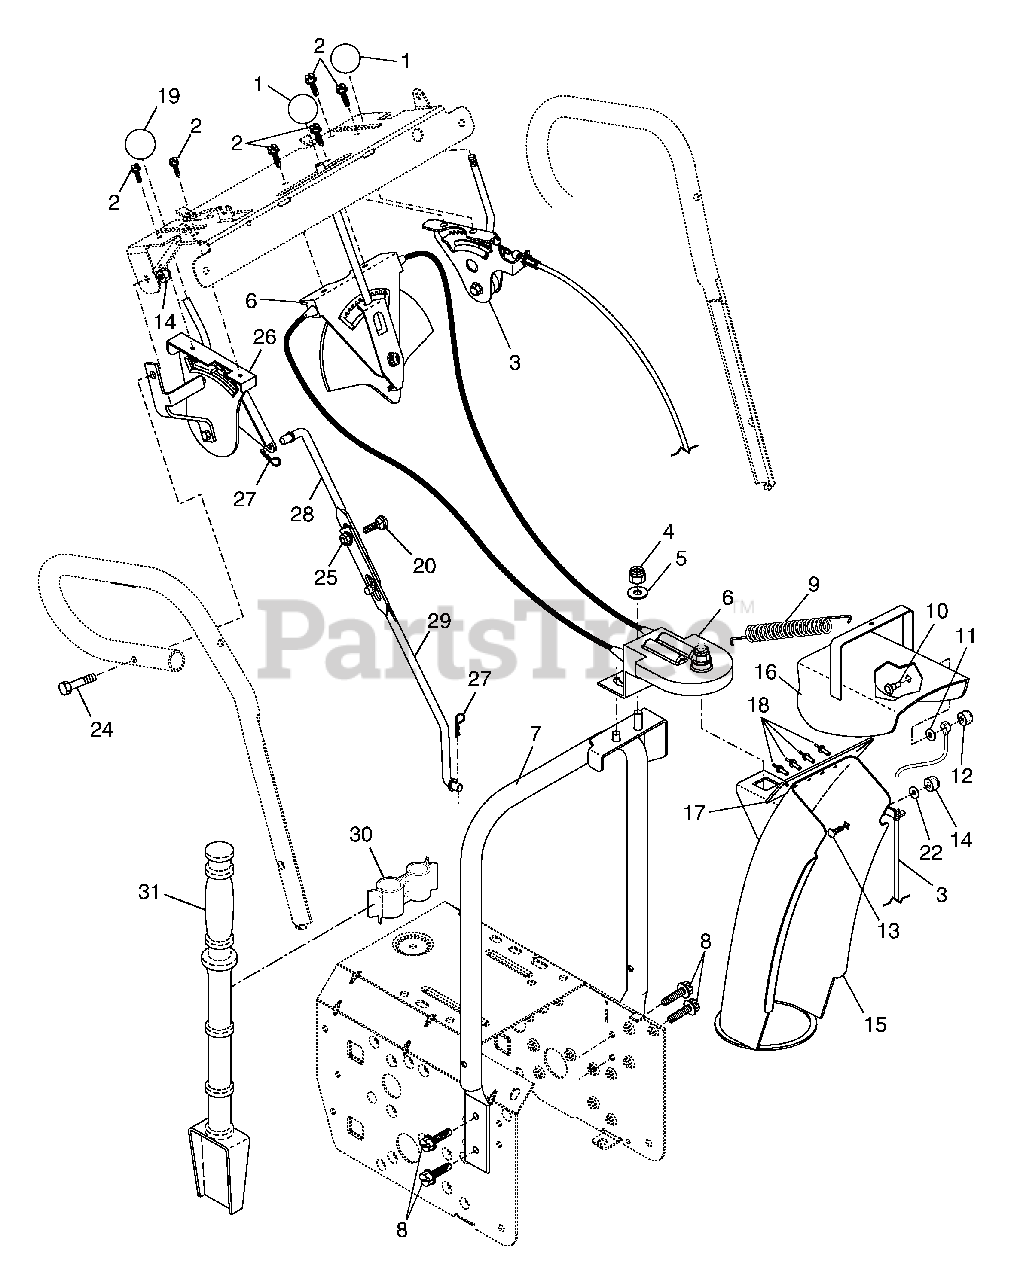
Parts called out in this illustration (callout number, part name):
1	Knob, Lever
2	Screw #10-24 x 5/8
3	Control Assembly, Deflector
4	Nut, Lock 3/8-16
5	Washer, Flat 3/8
6	Control Assembly, Chute Rotater
7	Support, Pivot
8	Screw, Hex Head 5/16-18 x 3/4
9	Spring, Deflector
10	Bolt, Shoulder
11	Washer, Friction, Nylon
12	Nut, Lock 1/4-20
13	Bolt, Carriage 5/16-18
14	Nut, Lock 5/16-18
15	Chute Assembly
16	Deflector Assembly
17	Seal, Deflector
18	Rivet, Blind
19	Knob, Speed Control Lever
20	Bolt, Carriage 5/16-18 x 3/4
22	Washer, Flat
24	Screw, Hex Head 5/16-18 x 1-3/4
25	Nut, Lock 5/16-18
26	Lever Assembly, Speed Control
27	Retainer, Hairpin
28	Rod, Upper, Speed Control
29	Rod, Lower, Speed Control
30	Clamp, Clean-Out Tool
31	Tool, Clean-Out
